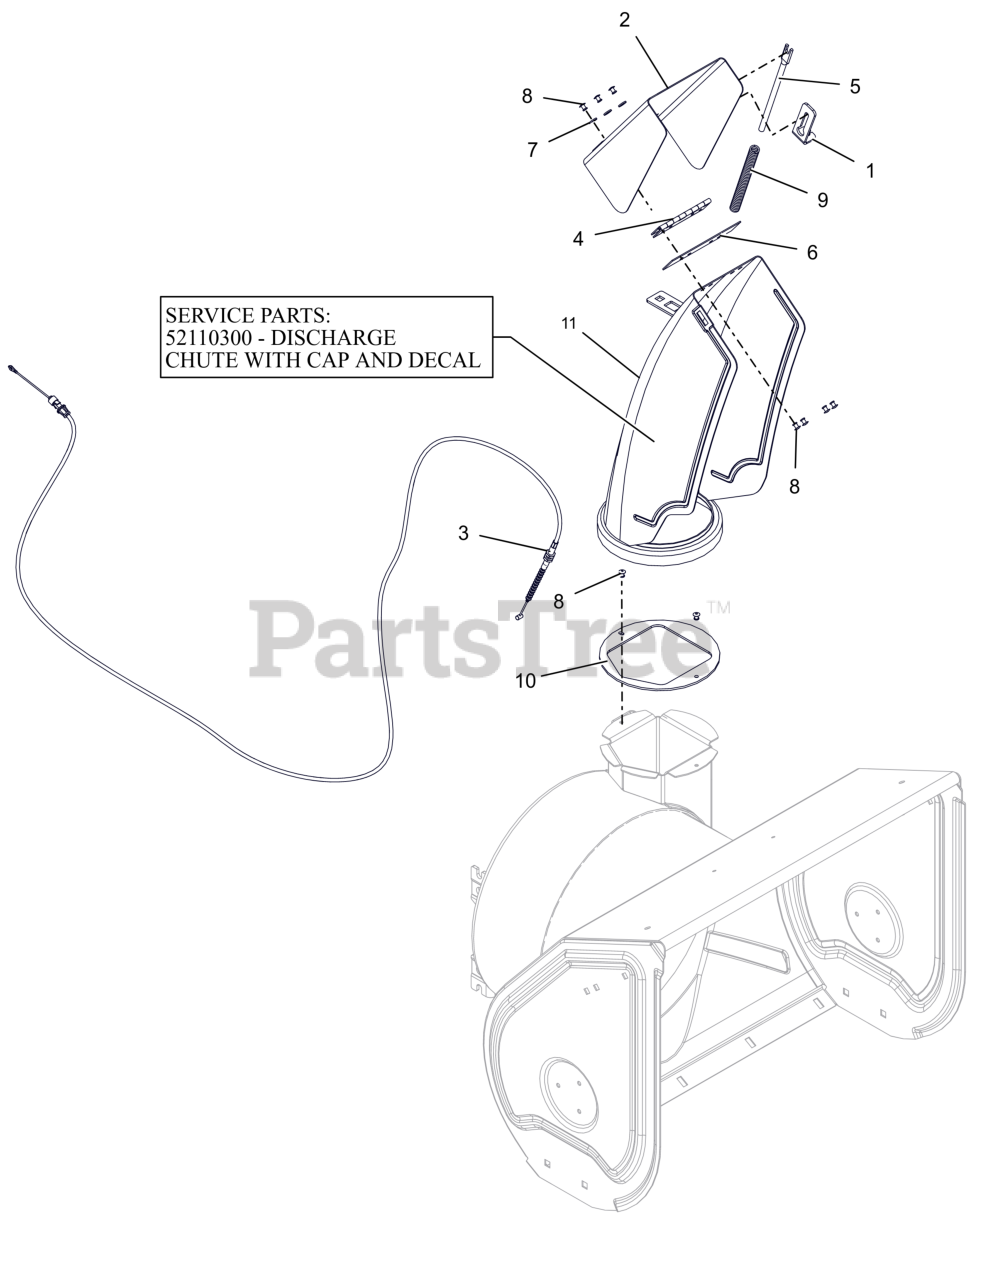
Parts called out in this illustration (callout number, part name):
1	BRACKET, ANCHOR-CHUTE CABLE
2	CAP, LARGE REMOTE W/DECAL
3	CABLE, DEFLECTOR - DELUXE
5	ROD, DEFLECTOR CAP
6	CAP SEAL 5.50
7	WSHR,FLT .196X.500X.066 ZCC
8	RVT, POP .1875 ZCC
9	SG-COMP .08X.40X6.50 14#/IN
10	BAFFLE, DISCHARGE NECK
11	CHUTE,DISCHARGE,RMT,ID
11	CHUTE, DISCHARGE W/CAP
